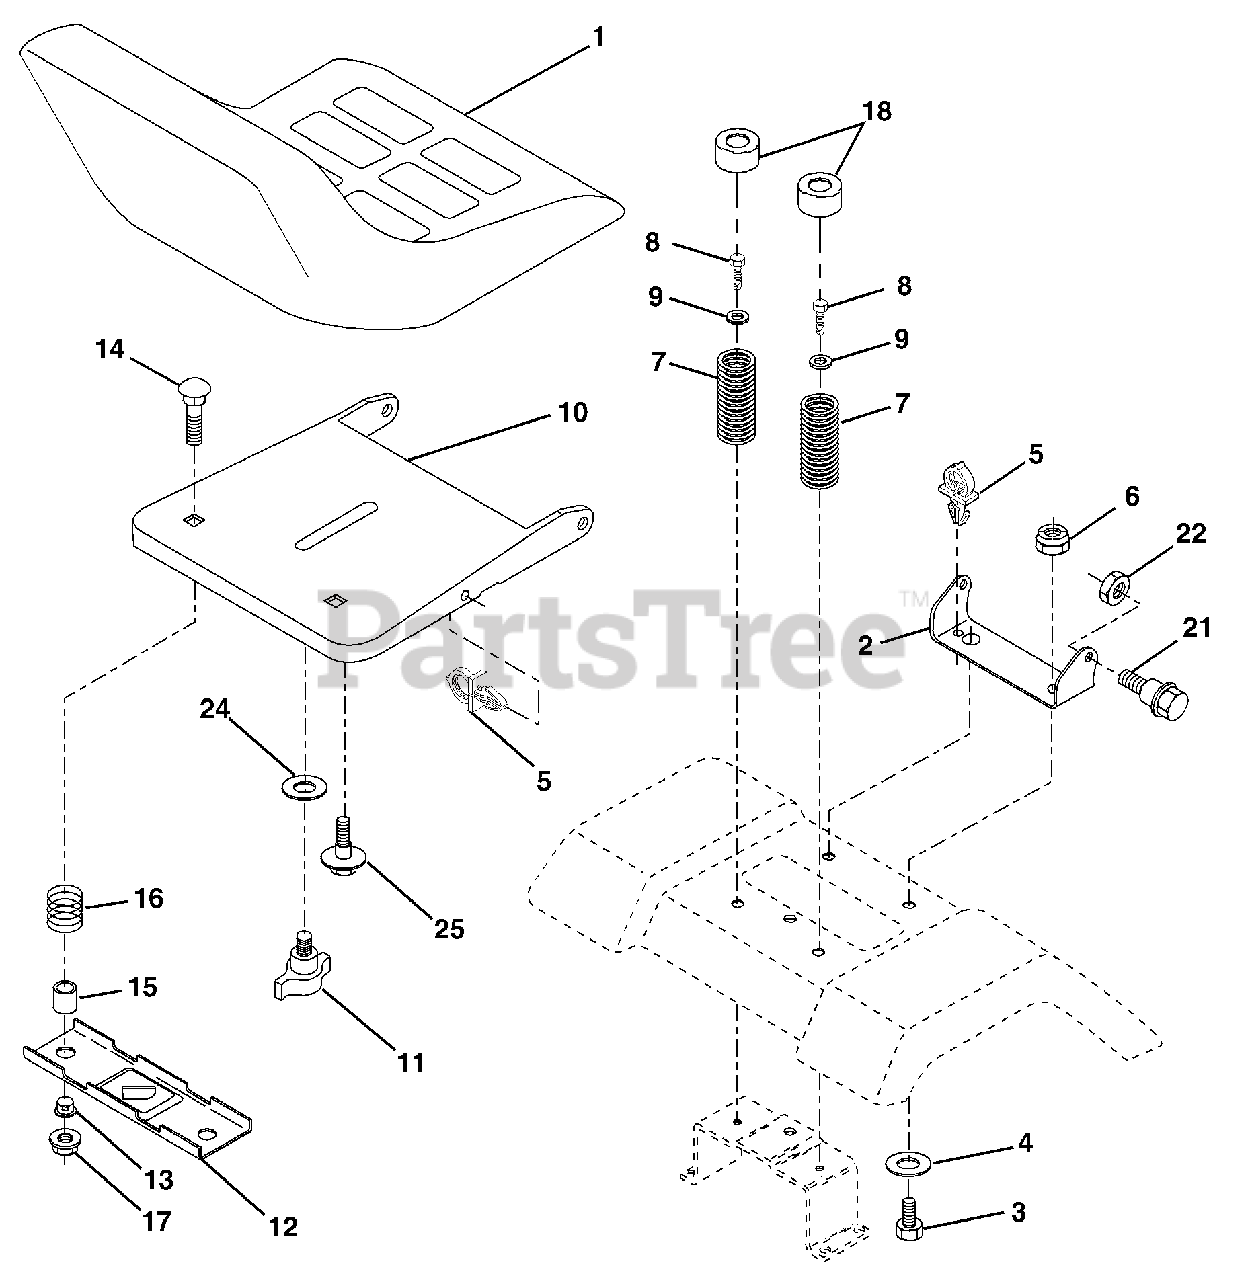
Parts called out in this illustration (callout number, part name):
1	Seat
2	Bracket Pivot Seat
3	Bolt Fin Hex 3/8-16 unc x 1
4	Washer 13/32 x 1 x 10 Ga
5	Clip Push-In
6	Nut Hex w/Ins. 3/8-16 unc
7	Spring Seat Cprsn
8	Screw 3/8-16 x 1-1/2
9	Washer 13/32 x 1 x 14 Ga.
10	Pan Seat
11	Knob Seat Adj. Wingnut
12	Bracket Mounting Switch
13	Bushing Snap Blk Nyl 50 Id
14	Bolt Rdhd Sqnk 1/4-20 x 1-1/2
15	Spacer Split 28x .88 Zinc
16	Spring Cprsn Plate 1.310 Ga
17	Nut Lock 1/4 Lge Flg Gr. 5 Zinc
18	Cap Spring Seat
21	Bolt Shoulder 5/16-18 unc
22	Nut Hex Lock W/Ins 5/16-18
24	Washer 17/32 x 1-3/16 x 12 Ga.
25	Bolt Shoulder 5/16-18 x 62
